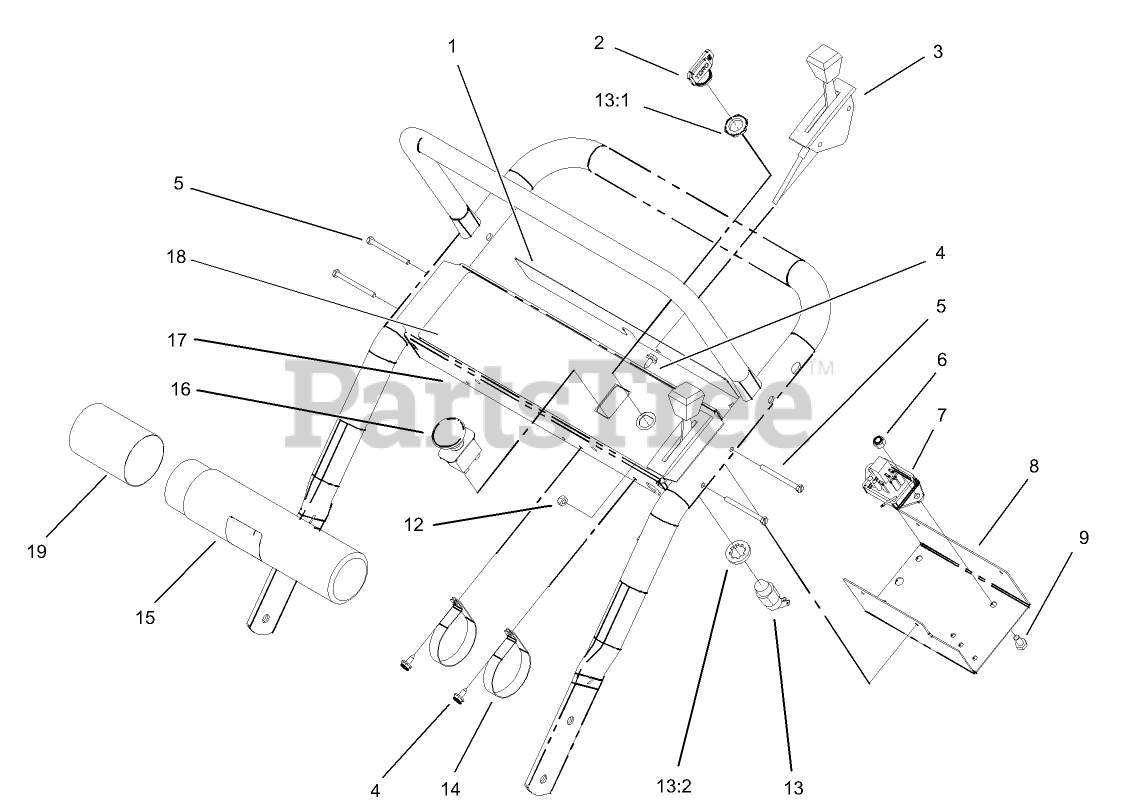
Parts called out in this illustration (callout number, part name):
1	DECAL-DANGER
2	KEY-IGNITION
3	CONTROL-THROTTLE
4	SCREW-HWHTF
5	SCREW-SHH
6	NUT-LOCK, NI
7	MODULE-DELAY
8	PANEL-BOTTOM
9	SCREW-HH
12	NUT-LOCK, NI
13	SWITCH-ON / OFF
13:1	NUT-HH
13:2	WASHER-TOOTH, INTERNAL
14	CLAMP-R
15	TUBE-MANUAL
16	SWITCH-PTO
17	PANEL-CONTROL
18	DECAL-CONTROL PANEL
19	CAP-HOUSING
